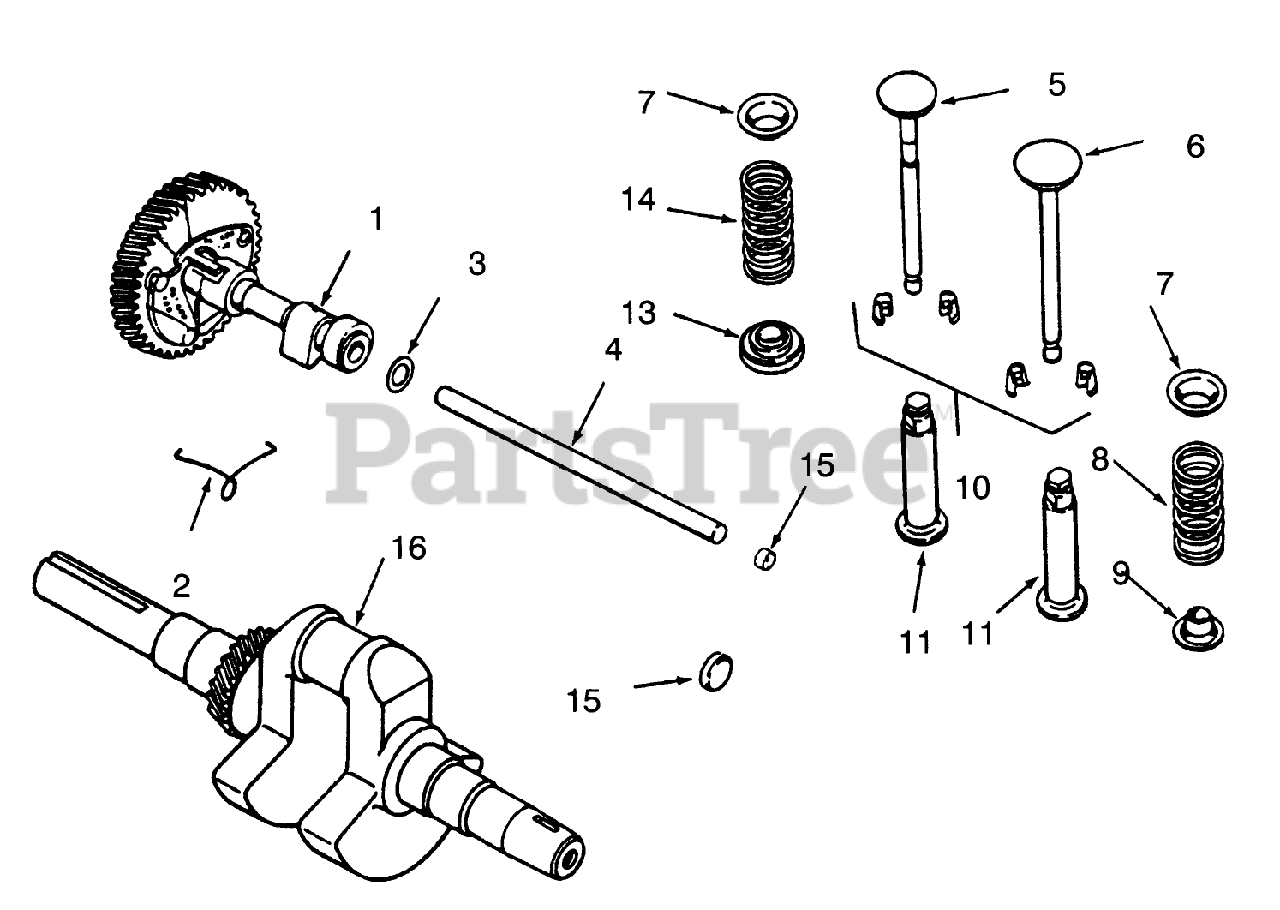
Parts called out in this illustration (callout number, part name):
1	KOHLER 47-010-11
2	KOHLER 47-089-01
3	KOHLER 275066
4	KOHLER 47-380-09
5	KOHLER 235838
6	KOHLER 235008
7	KOHLER 235011
8	KOHLER 235168
9	KOHLER 230011
10	KOHLER 41-755-10
11	KOHLER D-235327
13	KOHLER 52-413-01
14	KOHLER 235010
15	KOHLER X-702-3
16	KOHLER 47-142-02
